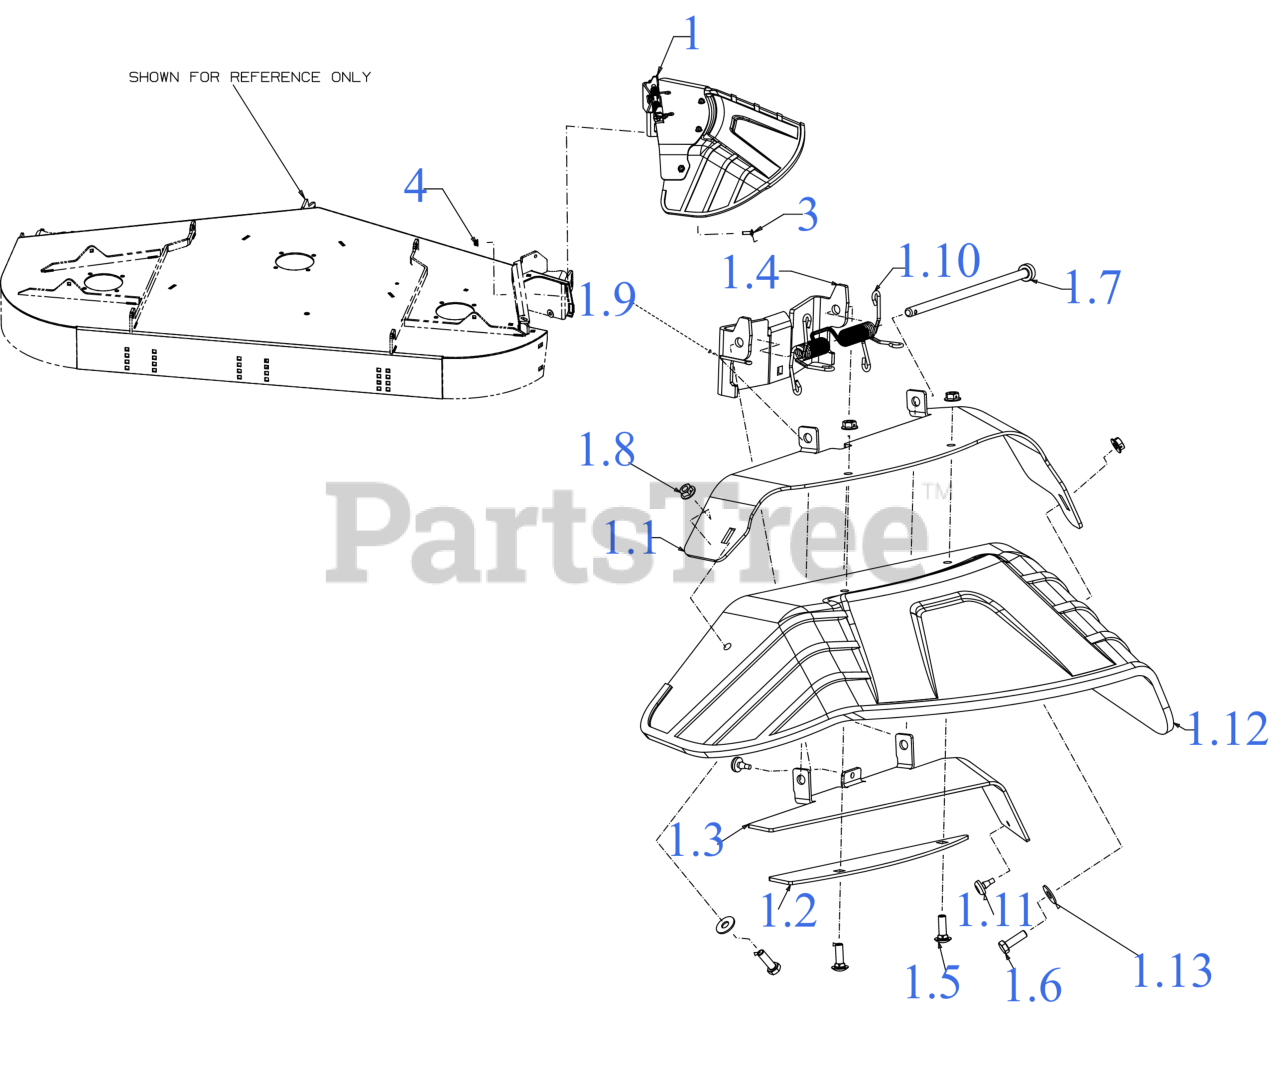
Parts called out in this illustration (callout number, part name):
1	DISCHARGE CHUTE ASSEMBLY
1.1	CHUTE BRACKET (TOP)
1.2	CHUTE BRACKET (BOTTOM)
1.3	CHUTE BRACKET (OPENING)
1.4	CHUTE BRACKET (MOUTING)
1.5	CARRIAGE BOLT 5/16-18 x 1.00
1.6	SCREW 5/16-18 x 1.0 GR5
1.7	HINGE PIN .375 x 9.0
1.8	HEX FLANGE NUT
1.9	COTTER PIN
1.10	TORSION SPRING
1.11	RUBBER BUMPER
1.12	FIBER FORMED CHUTE
1.13	FLAT WASHER
3	CARRIAGE BOLT 5/16-18 x 1.00
4	FLANGE LOCK NUT 5/16-18
